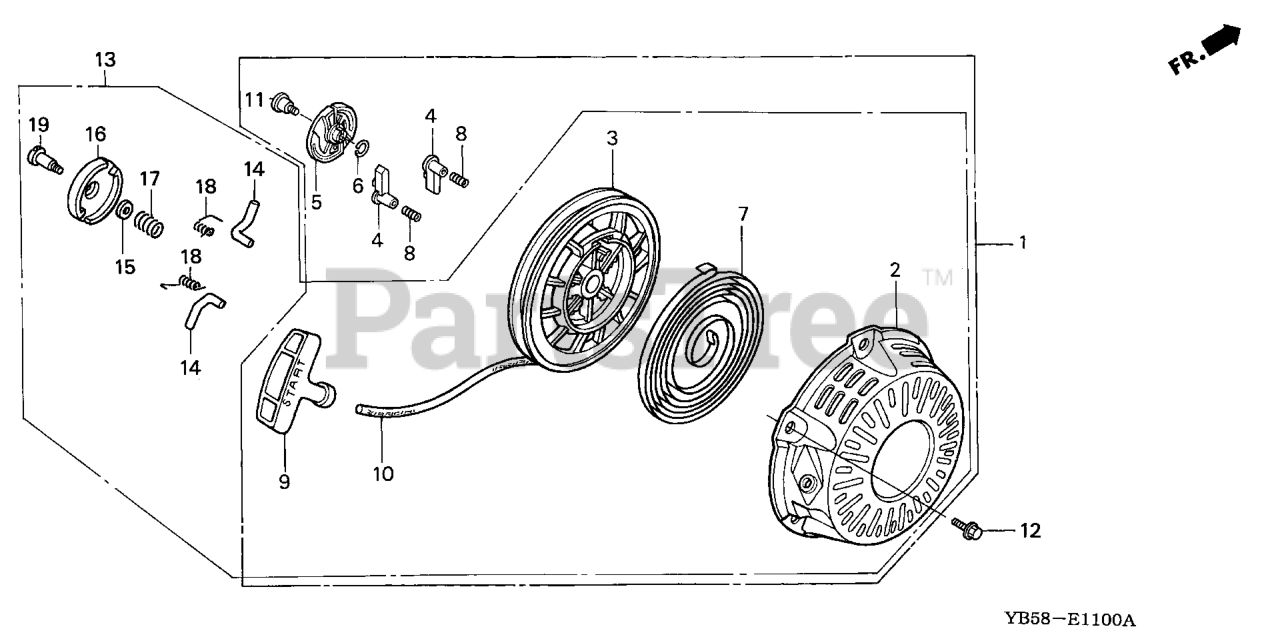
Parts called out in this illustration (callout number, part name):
1	STARTER ASSY., RECOIL *R280* (POWER RED)
2	CASE, RECOIL STARTER *R280* (Honda Code 7346836). (POWER RED)
3	REEL, RECOIL STARTER (NATURAL) (ENGINE NO.)
4	RATCHET, STARTER
5	GUIDE, RATCHET (ENGINE NO.)
6	SPRING, FRICTION (ENGINE NO.)
7	SPRING, RECOIL STARTER
8	SPRING, RETURN (ENGINE NO.)
9	GRIP, STARTER
10	ROPE, RECOIL STARTER (#5X55")
11	SCREW, SETTING (ENGINE NO.)
12	BOLT, FLANGE (6X10)
